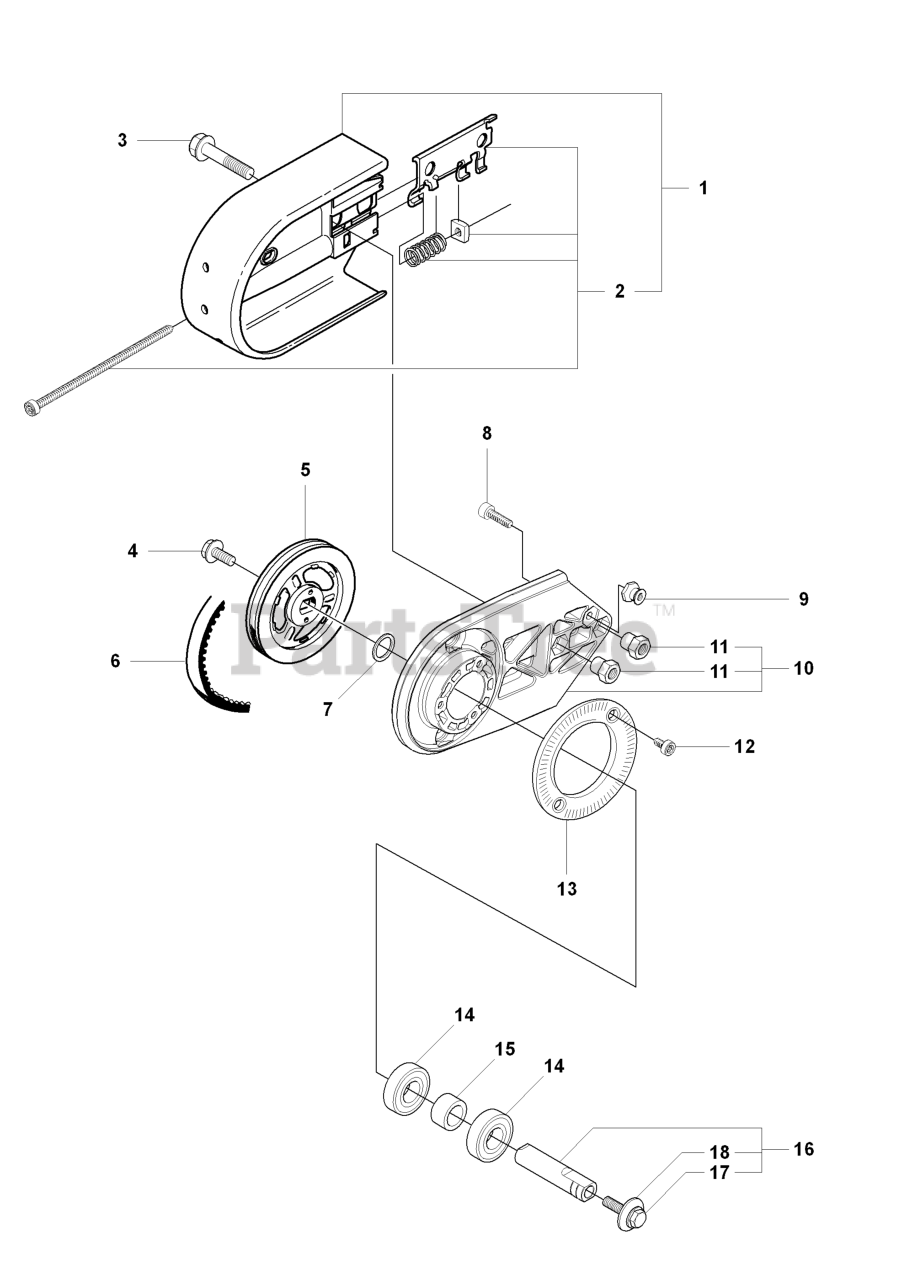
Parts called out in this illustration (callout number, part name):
1	COVER
5	%PULLEY
6	%V-BELT
7	WASHER 15X21
8	SCREW MC6S 5X16
10	HOUSING
14	BALL BEARING
16	SHAFT
17	SCREW
18	WASHER
